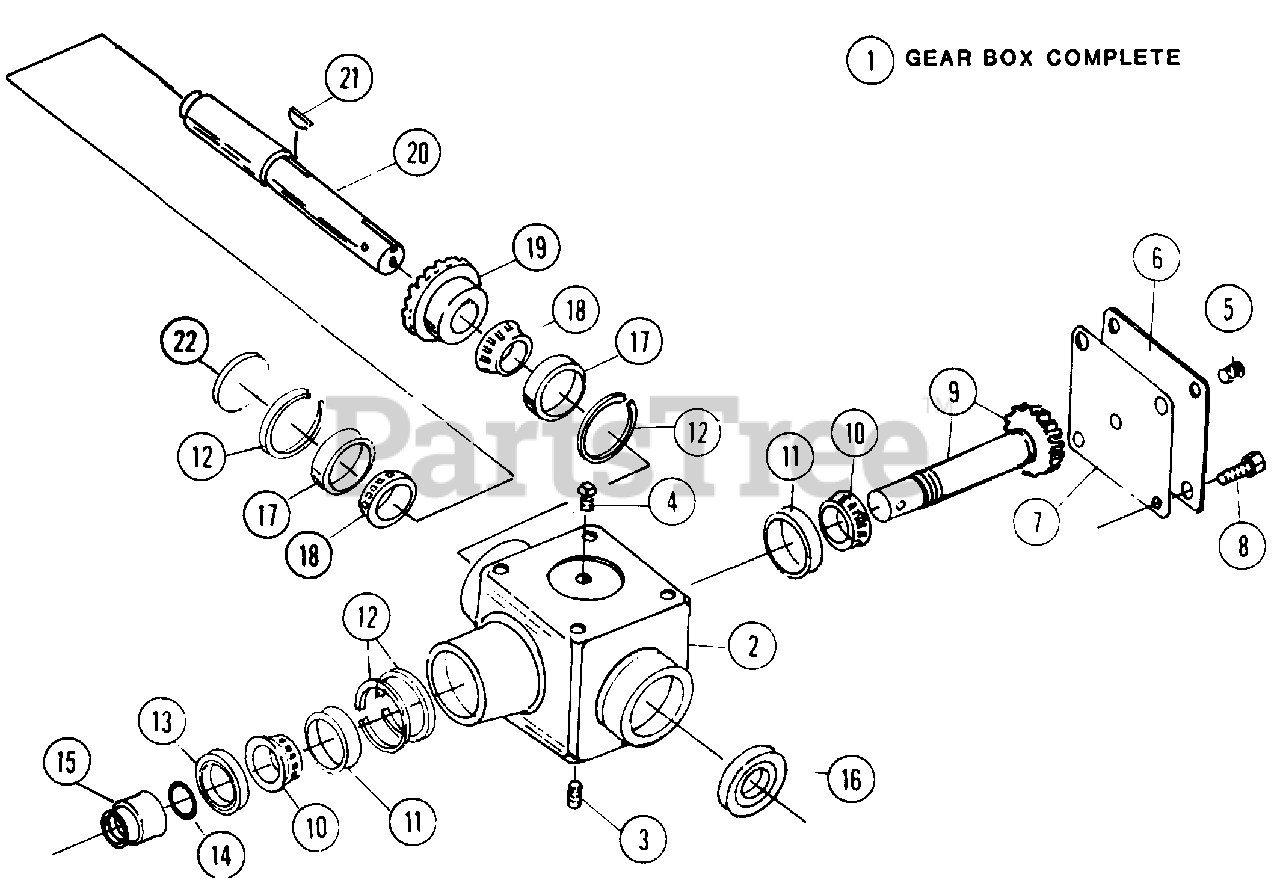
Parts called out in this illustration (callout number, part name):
1	GEAR BOX - COMPLETE (Durst #4477)
2	HOUSING, GEAR BOX
3	PLUG, DRAIN 3/8-18 NPT
4	PLUG, VENT 3/8-18 NPT SQUARE HEAD
5	PLUG, CHECK 1/8-27 NPT
7	GASKET, COVER
8	SCREW, 5/16-18 x 1/2 HEX HEAD CAP
9	SHAFT, BEVEL PINION
10	BEARING CONE
11	BEARING CUP
12	RING, RETAINING
13	SEAL, OIL 32MM x 46MM x 8MM
14	O-RING (National #NS118)
15	STAKE-NUT
16	SEAL, OIL 34" ID
17	BEARING CUP
18	BEARING CONE
19	GEAR, BEVEL 28T-10P
20	SHAFT, OUTPUT
21	KEY, WOODRUFF
22	CAP, END
